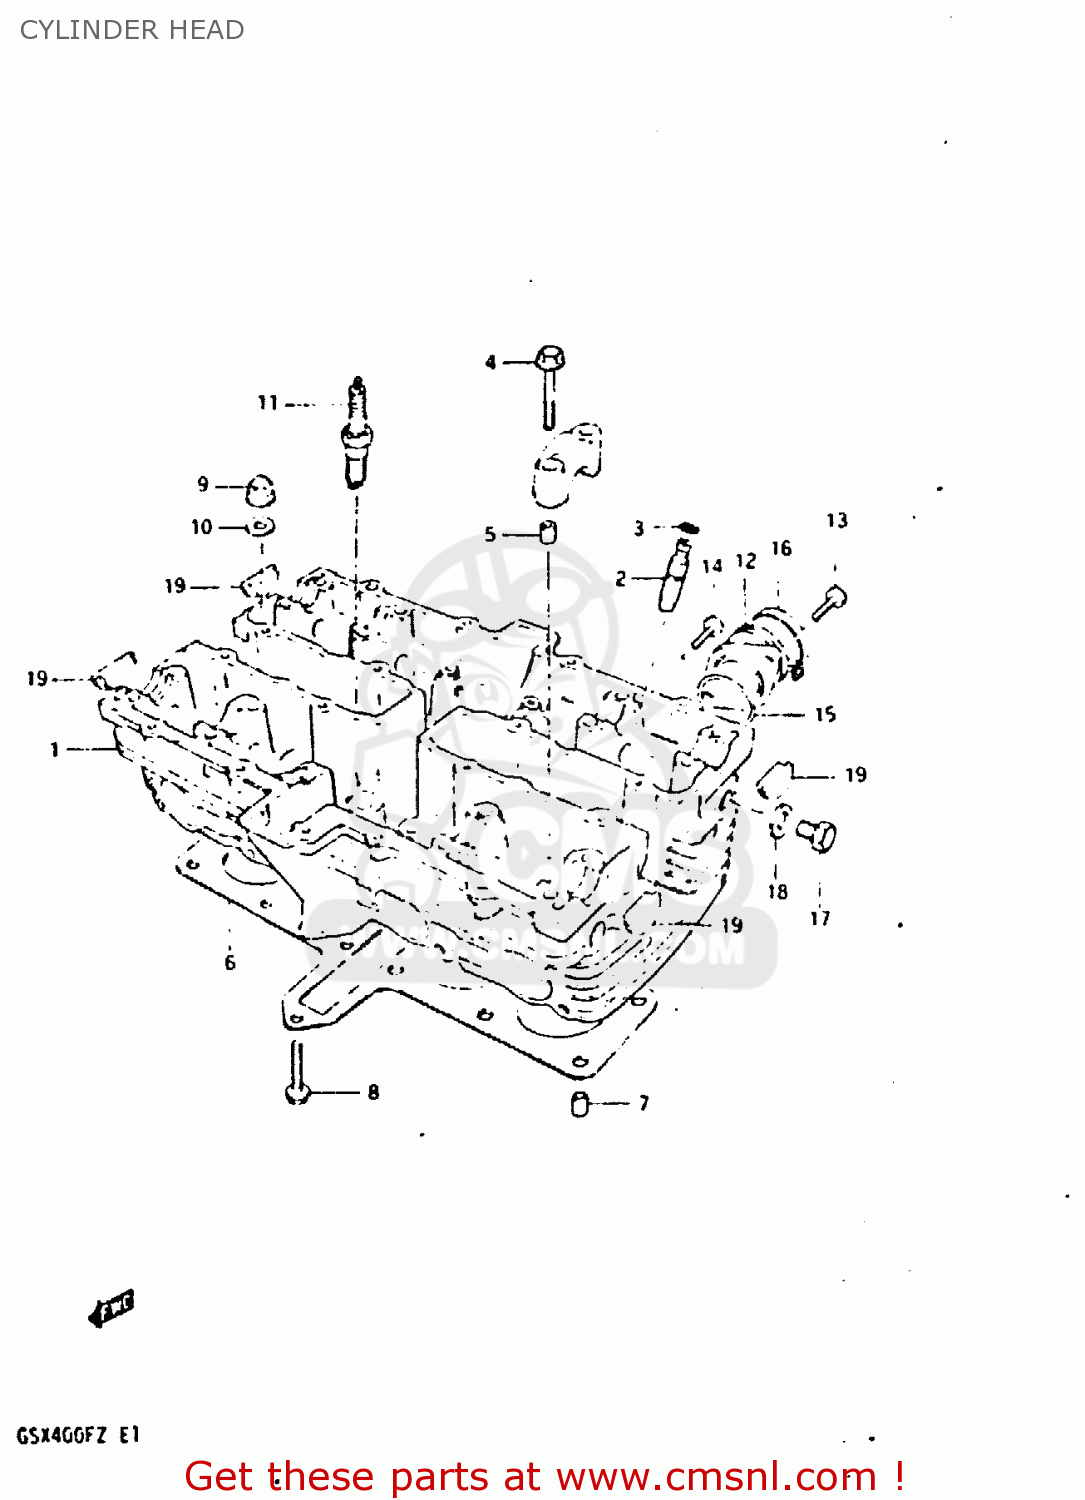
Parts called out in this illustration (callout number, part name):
1	CYLINDER HEAD SET
2	GUIDE, INTAKE VALVE
3	RING,SNAP
4	BOLT(6X39)
5	PIN(6.2X8X11)
6	GASKET
7	PIN
8	BOLT
9	NUT
10	GASKET(8.5X20X2.3) (NAS)
11	SPARK PLUG DR8ES-L
12	PIPE, INTAKE
13	SCREW
14	SCREW
15	O RING(D:2.4,ID:31.7)
16	CLAMP
17	PLUG (14X12)
18	GASKET(14X19.2X2) (NAS)
19	PLUG
